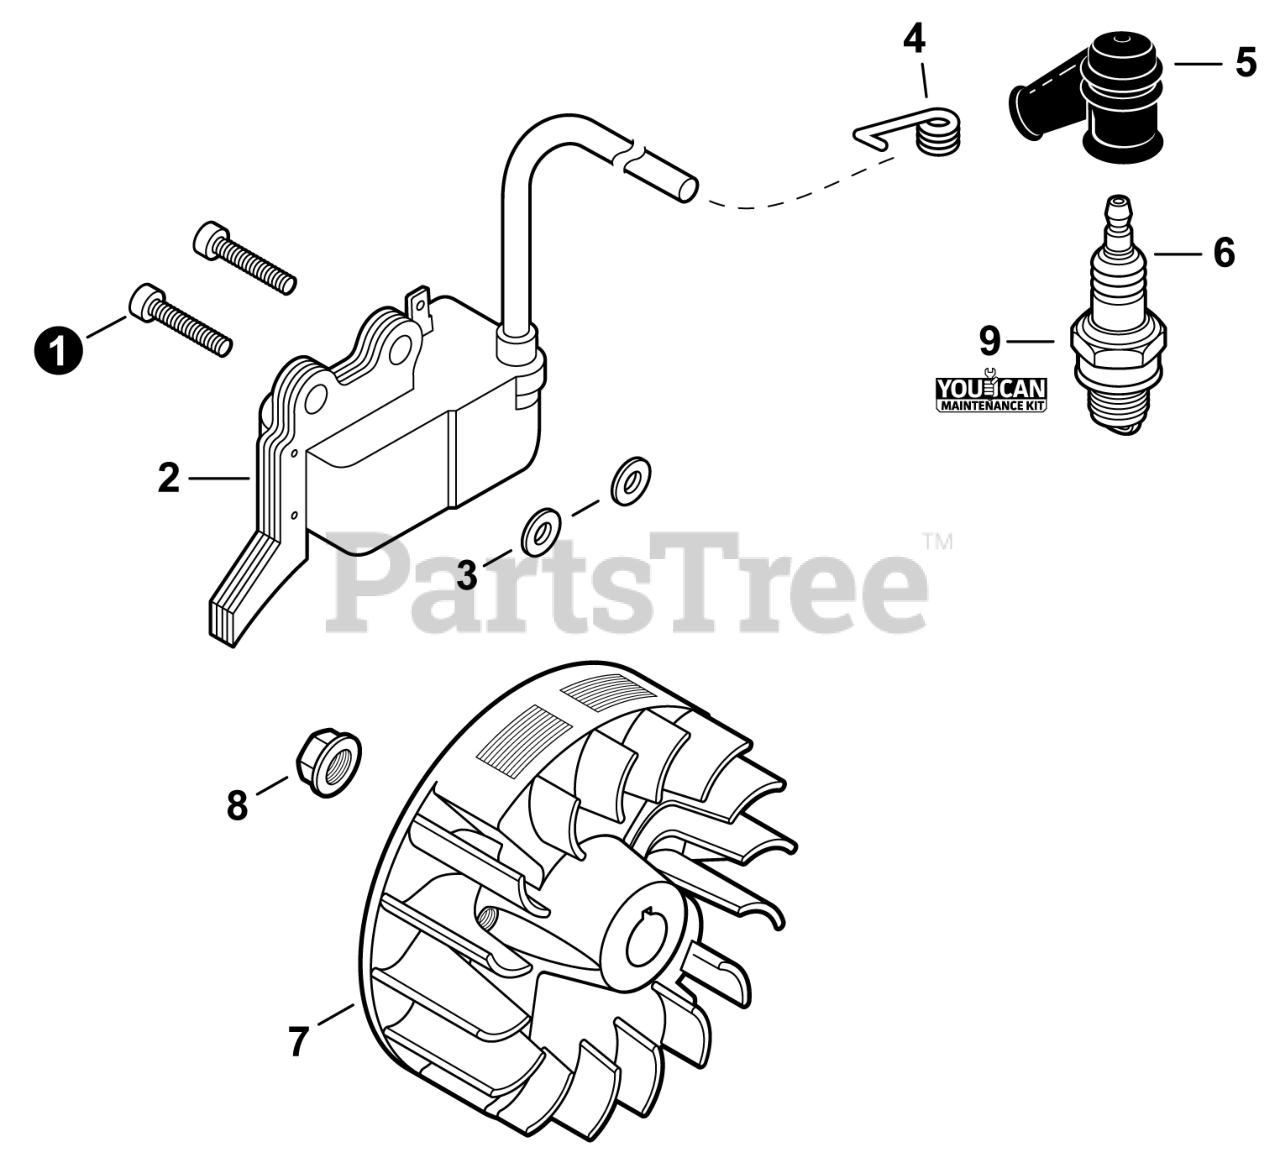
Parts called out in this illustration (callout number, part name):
1	BOLT, TORX 5x20
2	COIL, IGNITION
3	SPACER 5
4	TERMINAL, SPARK PLUG
5	CAP, SPARK PLUG
6	SPARK PLUG - BPMR8Y
7	FLYWHEEL
8	NUT, FLANGE M8
9	TUNE-UP KIT - YOUCANT
